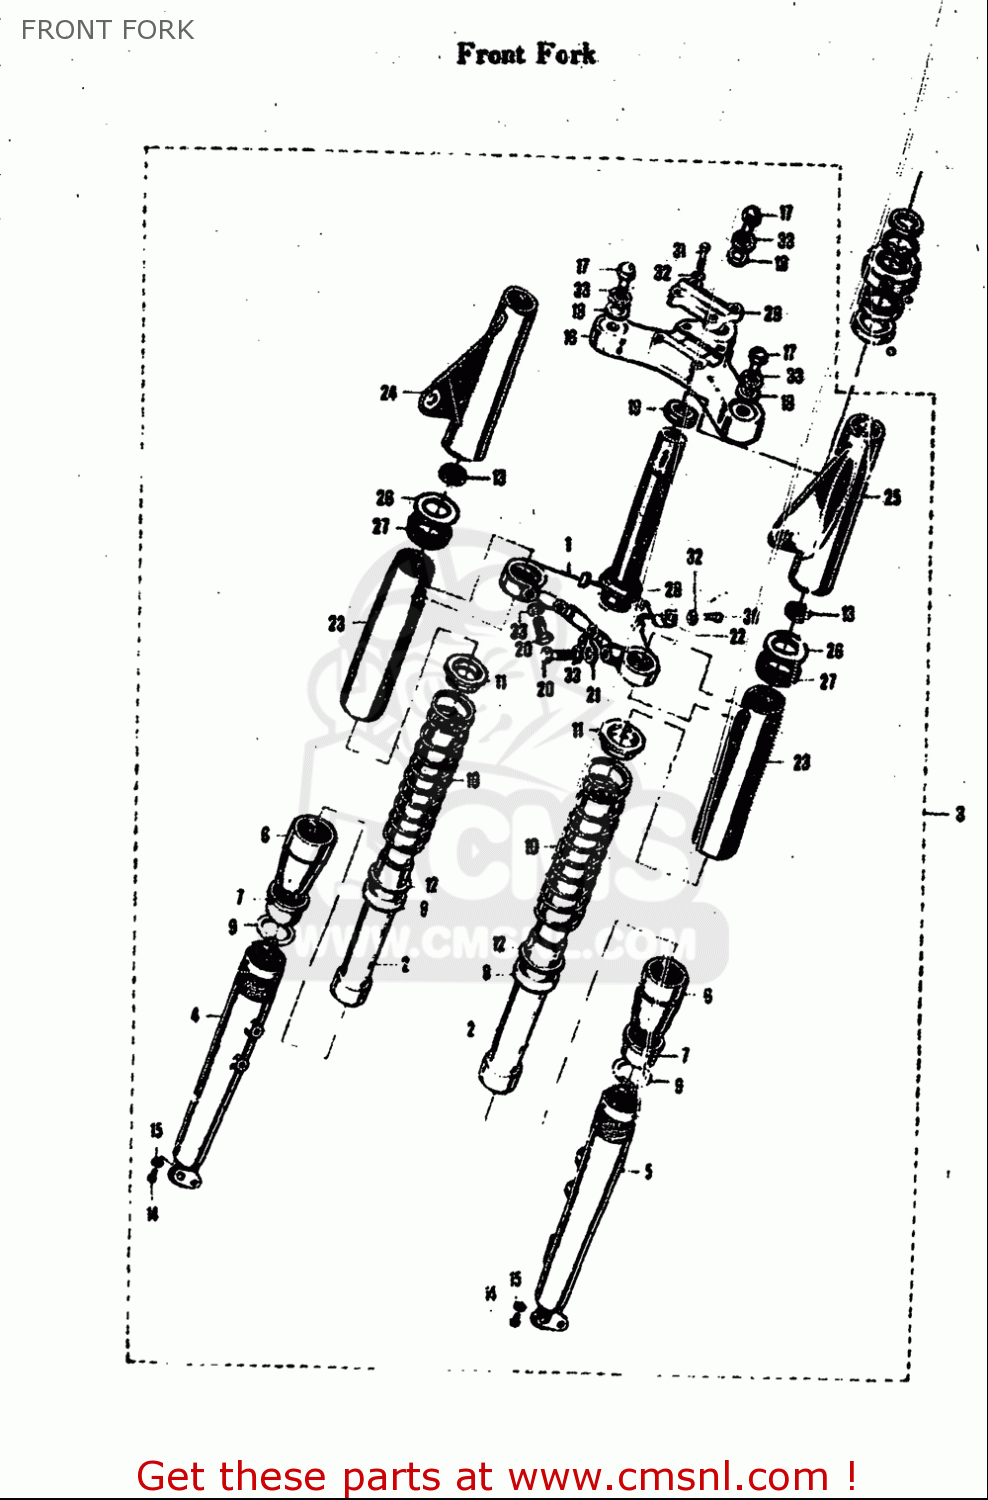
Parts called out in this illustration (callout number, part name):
7	GUIDE,FORK INNER TUBE
14	OIL DRAIN PLUG
15	GASKET,DRAIN,PLUG (NAS)
17	BOLT,FR FORK
18	WASHER,STEERING STEM HEAD
20	BOLT
21	CLIP,SPEEDOMETER CABLE
22	CLIP,BRAKE CABLE
31	BOLT
32	WASHER,LOCK
